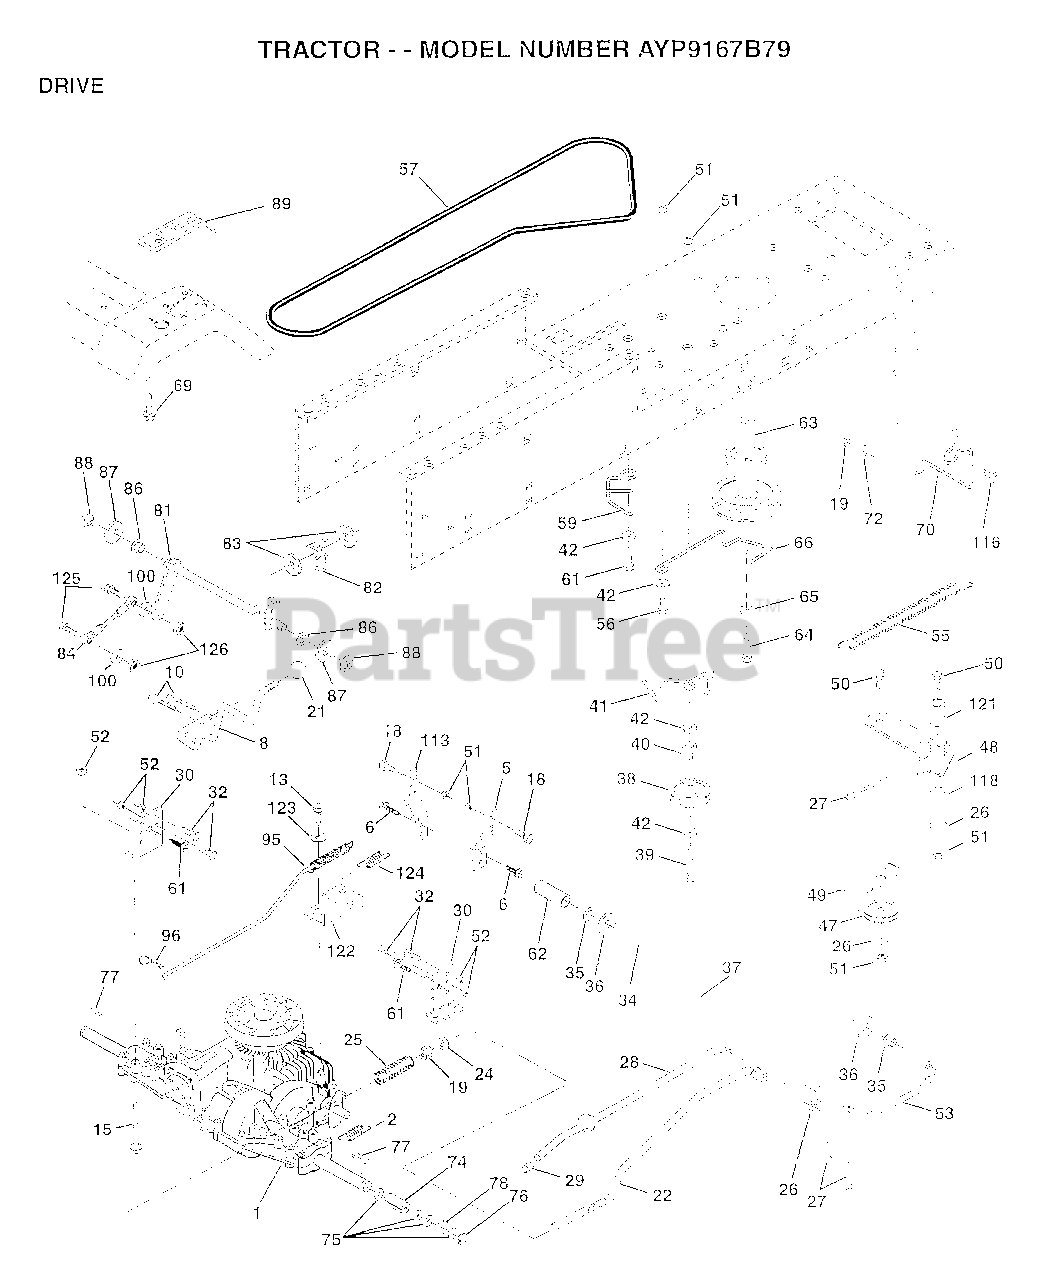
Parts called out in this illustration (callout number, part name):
1	TRANSAXLE, PEERLESS
2	SPRING.BRAKE.RETU
6	SCREW
8	ROD SHIFT FEND YT
10	PIN COTTER 1/8
13	BOLT.1/4-28.W/PAT
15	BOLT.HX.FLG.5/16
18	BOLT
19	NUT
21	KNOB T (1/2-HOLE)
22	BRAKE ROD
24	NUT
25	SPRING ROD LT
26	WASHER
27	COTTER PIN
28	ROD.BRAKE.PARK.LT
30	TRANSAXLE MTG BKT
32	BOLT
34	SHAFT ASM-PEDAL F
35	NYLON BEARING
36	WASHER LT
38	PULLEY.IDLER.FLAT
39	BOLT
40	SPACER T
42	WASHER
48	BELLCRANK ASM
49	RETAIN BELT
53	"LINK, CLUTCH T"
55	"SPRING, RETURN LT"
57	"V-BELT,GRD DRIVE"
59	KEEPER BELT CNTSP
61	SCREW
62	PEDAL COVER T
63	PULLEY.ENGINE
64	BOLT
65	LOCKWASHER
66	KEEPER-BELT
69	SCREW HEXWSH H-L
70	KEEPER BELT ENG
72	WASHER
75	WASHER
76	E-RING LT
77	SQUARE KEY
78	WASHER
81	SHAFT ASM CROSS
82	"SPRING,TORSION"
83	WASHER
84	"ROD TIE, PVST 20"""
86	BUSHING
87	WASHER D
88	KLIP RING
95	ROAD ASM BYPASS
96	RETAINER M
100	WASHER M
113	"STRAP,TORQUE"
116	BOLT RDHD 3/8-16
118	SPACER-BELLCRANK
121	NYLINER-CLUTCHING
122	"PLATE-BYPASS,PVST"
123	WASHER
124	SPRING RETURN
